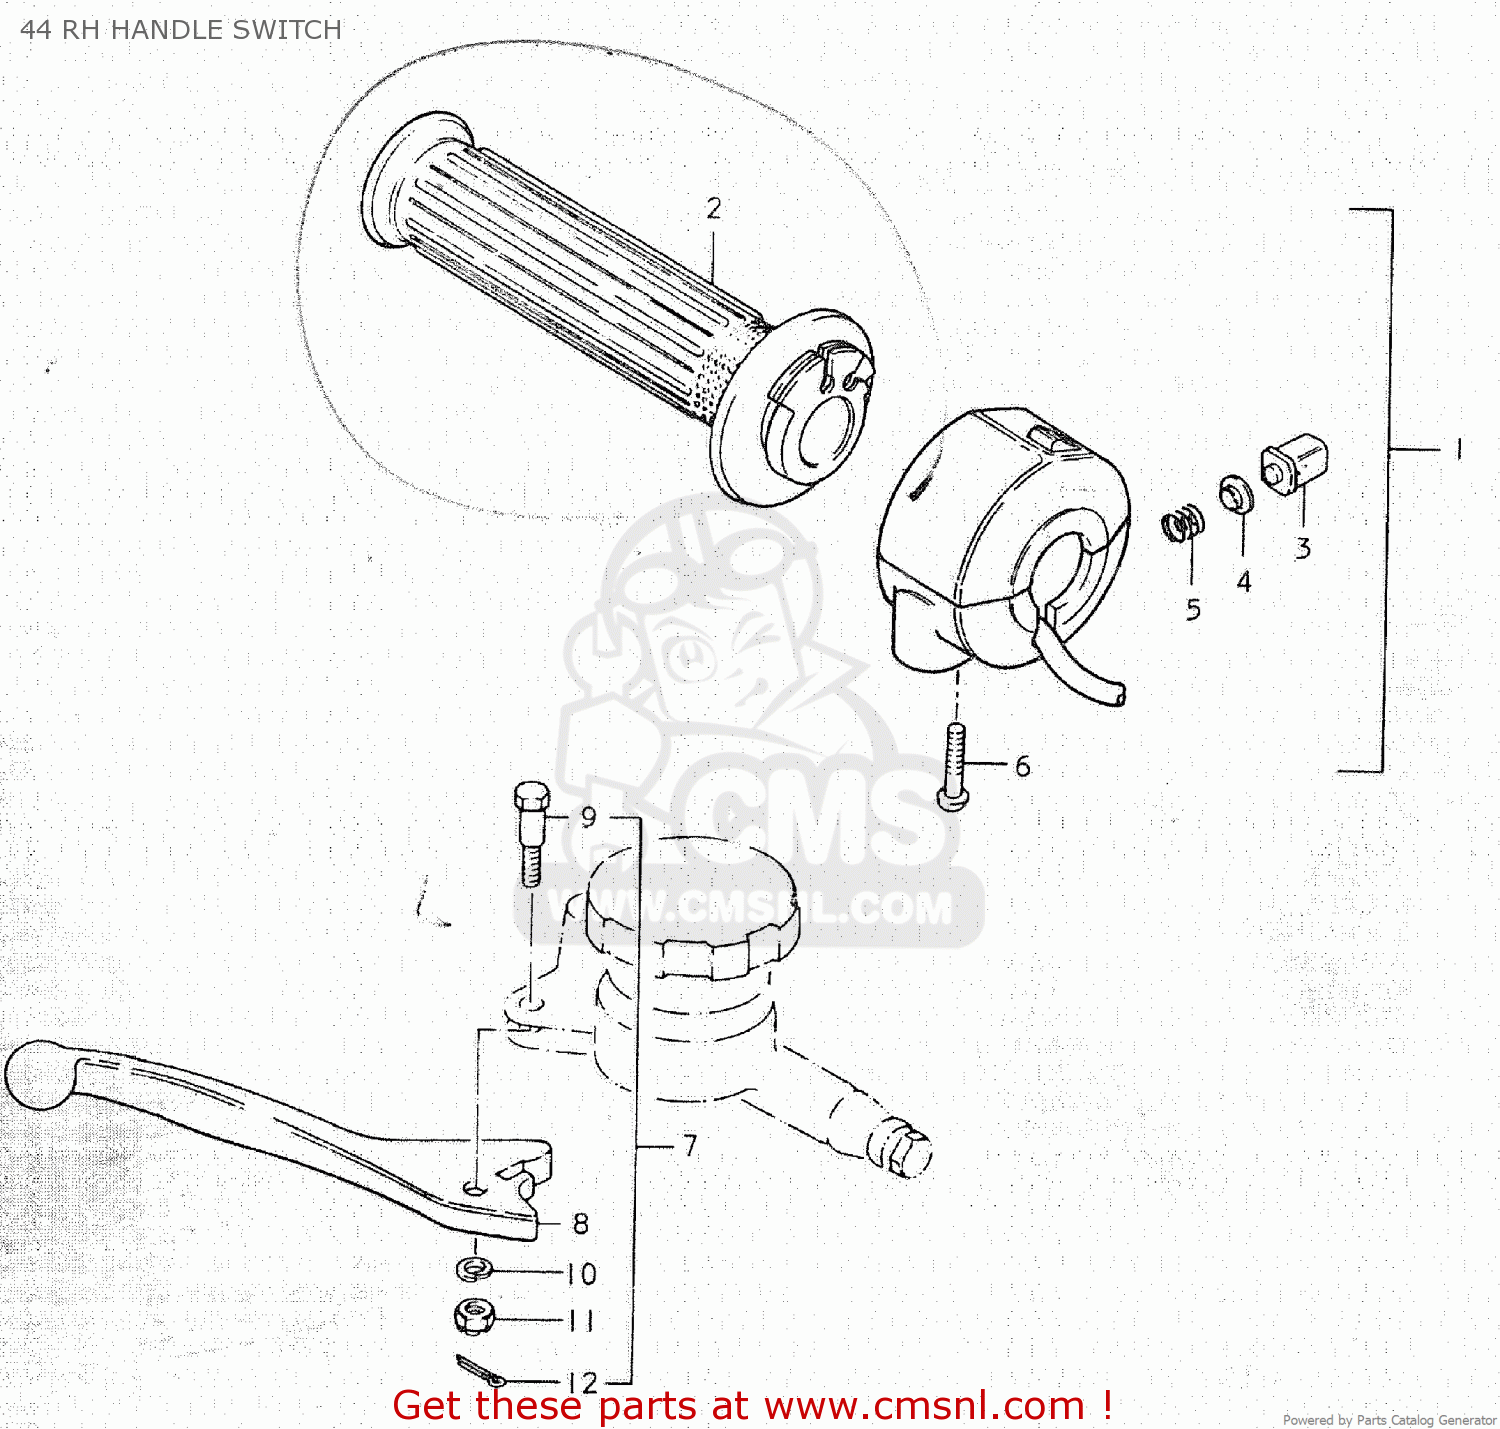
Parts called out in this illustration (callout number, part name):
1	CASE ASSEMBLY,THROTTLE
2	GRIP,THROTTLE
3	BUTTON,HORN
4	CONTACT
5	SPRING
6	SCREW
7	LEVER ASSEMBLY,BRAKE
8	LEVER,BRAKE
9	BOLT,LEVER
10	LOCK WASHER
11	NUT,LEVER FITTNG
12	COTTER PIN
